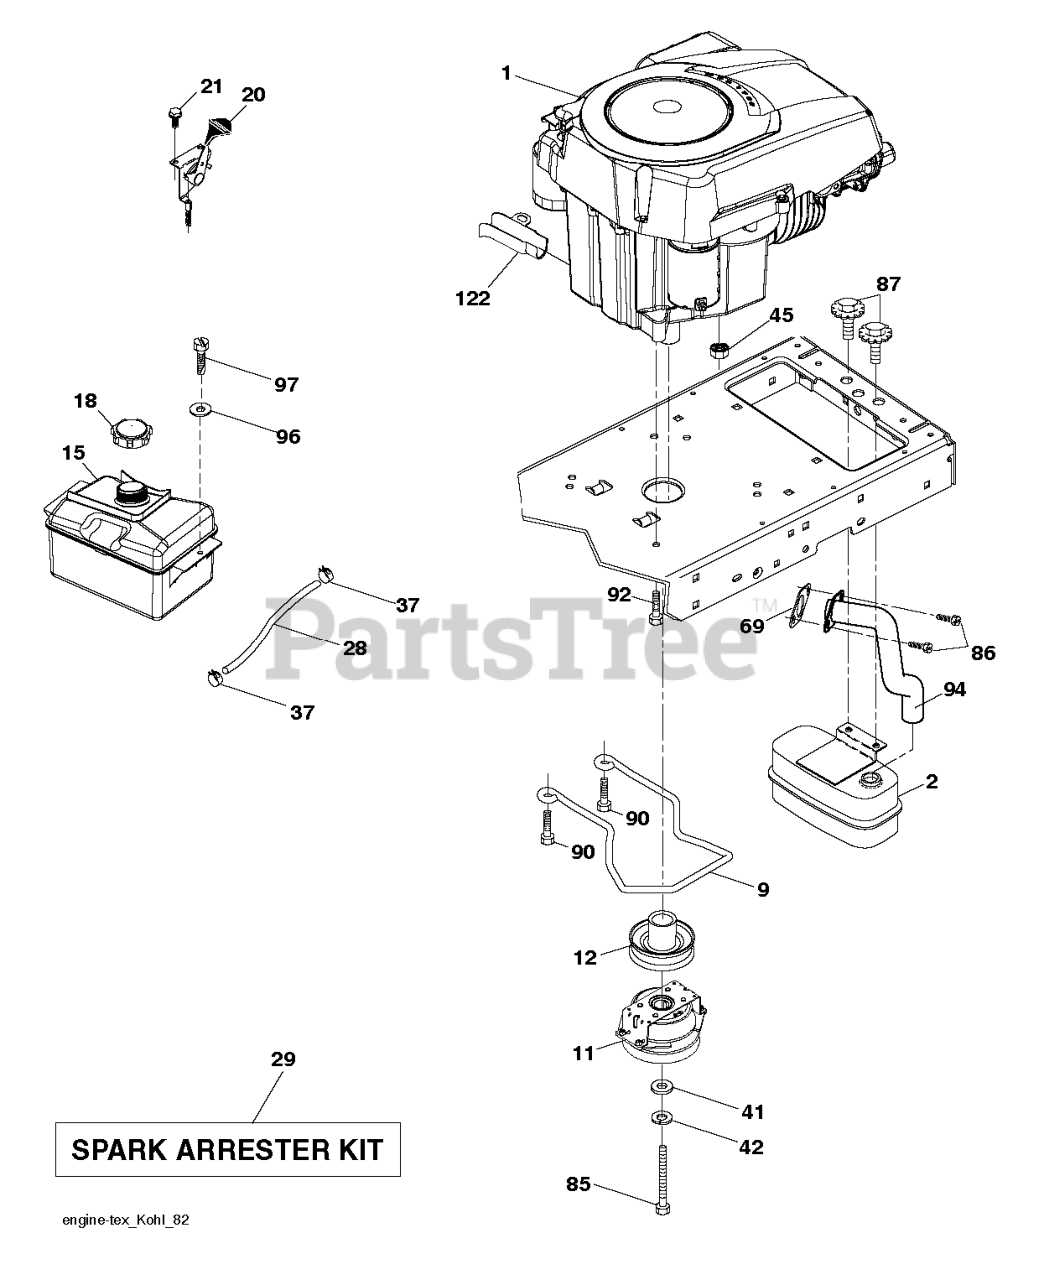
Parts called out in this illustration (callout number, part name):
2	MUFFLER.ASM.SNGL.XTNDED.DFLCTR
9	KEEPER.BELT.ENG.4.25"2.BLT.431
11	CLUTCH.OGURA.4.4PD.GT1.5-EH13V
12	PULLEY.ENGINE.TUFFTORQ
15	FUEL.TANK.ASM.NON-EPA
18	CAP ASM.FUEL.2.25"FR.
20	CONTROL.TH/CK.C.
21	SCREW.#10 X 0.750.BOS
28	LINE.FUEL.20
29	KIT.SPARK ARRESTOR 794945 B&S
37	HOSE CLAMP
42	WASHER 7/16 LOCK
45	NUT
69	GASKET.EXHAUST.KOHLER
85	CLUTCH BOLT7/16-20X3.5 GR524HR
86	NUT.HEX.FLANGE.TOPLOCK
87	BOLT.5/16-18UNCX3/4 W/SEMS.BLK
90	SCREW 3/8-16X1
92	SCREW 3/8-16X1
94	TUBE.EXHAUST.KOHLER 5400
97	SCREW HEXWSHR 1/4-20X3/4
122	EXTENSION DRAIN OIL
